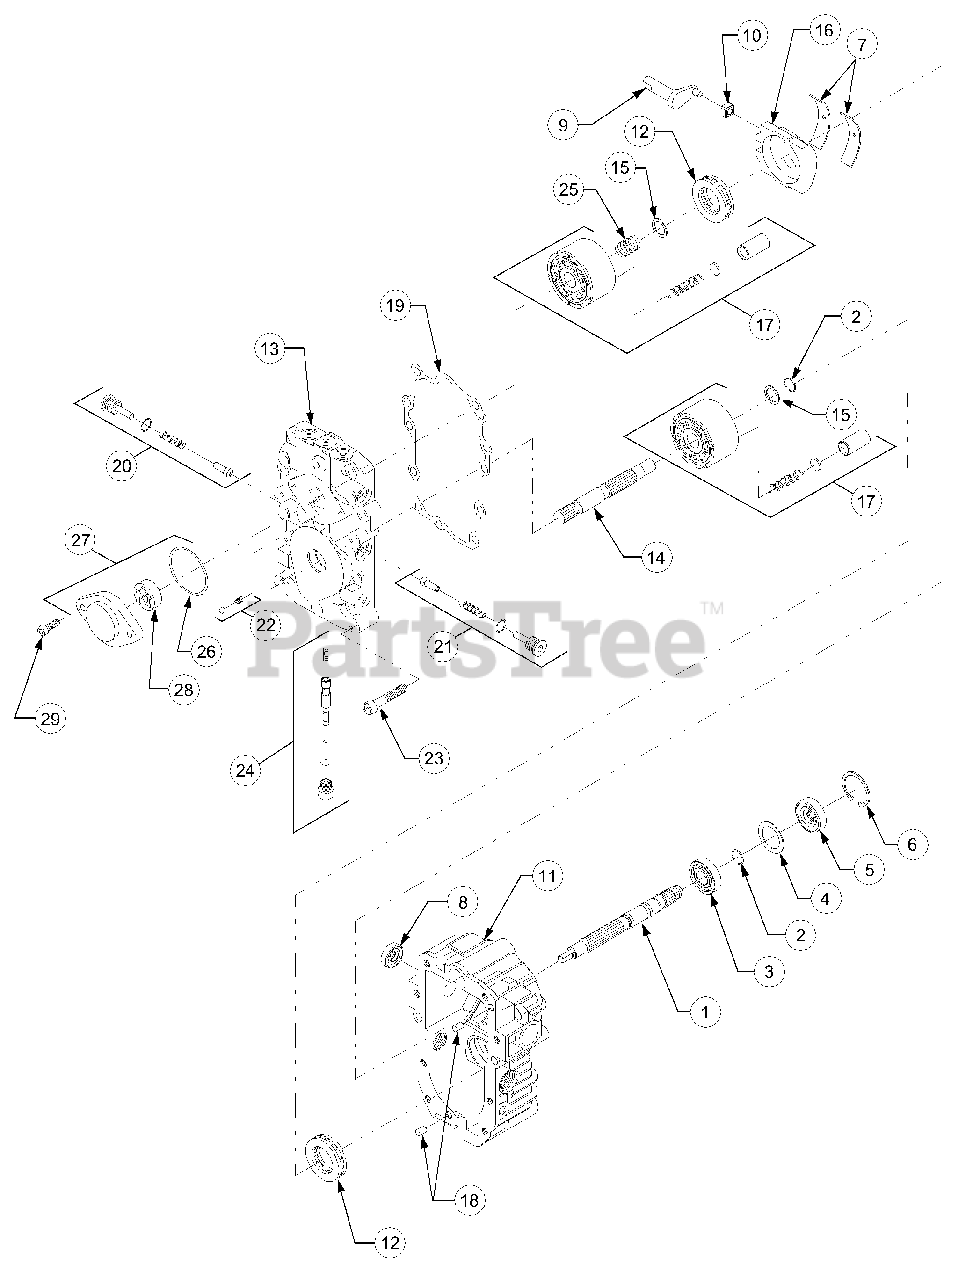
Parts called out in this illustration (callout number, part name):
1	Shaft, Pump
2	Ring, Retaining
3	Bearing, Ball
6	Ring, Retaining
7	Bearing, Cradle
9	Arm, Trunnion
10	Guide, Slot
11	Housing Kit
12	Bearing Assembly, Thrust Ball
13	Center Section Kit
14	Shaft, Motor
15	Washer, Block Thrust
16	Swash Plate
17	Block Assembly
19	Gasket, Center Section
20	Kit, Check Valve
21	Kit, Orificed Check Valve
22	Kit, Charge Relief Valve
23	Screw, Socket Hd
24	Kit, Bypass Valve
25	Spring, Block
27	Kit, Charge Pump
28	Gerotor Assy
29	Screw, Socket Hd
